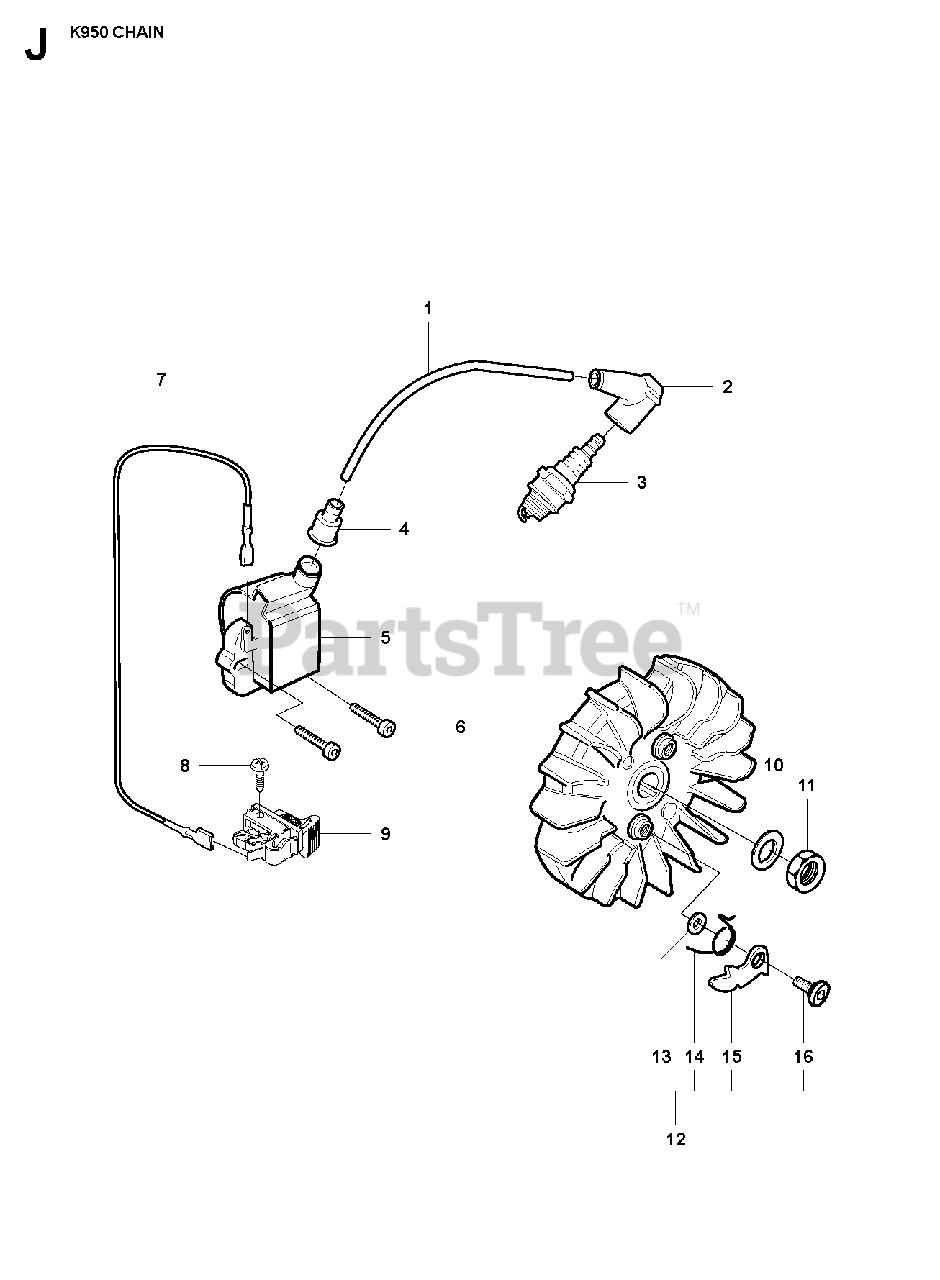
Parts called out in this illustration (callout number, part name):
1	IGNITION CABLE
2	SPARK PLUG CAP
3	SPARK PLUGRCJ 7Y
5	IGNITION SYSTEM
8	SCREW CCRPANT
9	STOP SWITCH
12	FLYWHEELIncl. 13, 14, 15, 16
